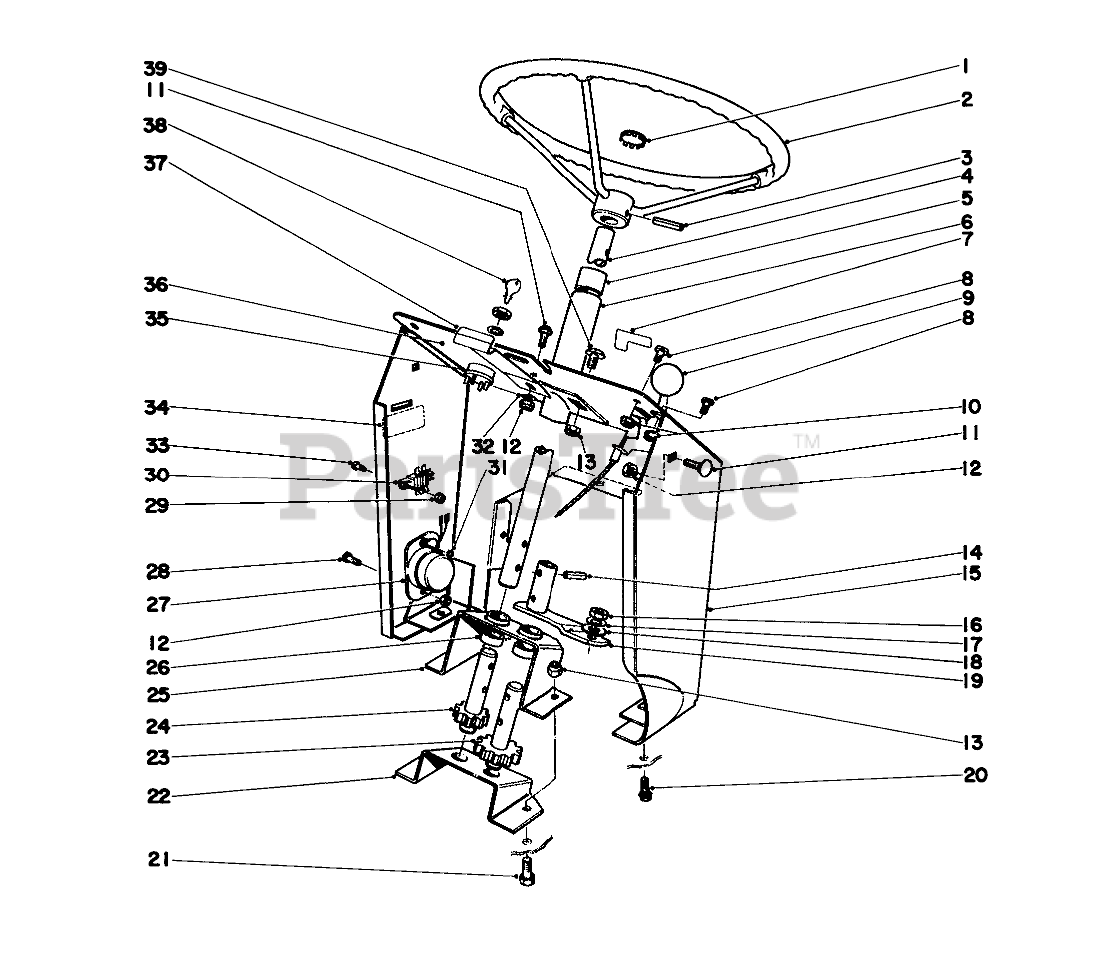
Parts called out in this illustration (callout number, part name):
2	Steering Wheel
3	PIN-ROLL
4	Shaft Steering
5	BUSHING
6	Steering Tube (Incl. Ref. #5)
7	Decal (Model 57003)
8	SCREW-PPH
9	Throttle Control
10	NUT-KEPS
11	SCREW-CARRIAGE
12	NUT-LOCK
13	NUT-LOCK, CONE
14	PIN-ROLL, SLOTTED
15	Rear Hood Support (Model 57003)
16	NUT-HEX
17	WASHER-LOCK
18	WASHER-FLAT
19	Steering Arm
20	1/4-20X5/8 THDG SEMS
21	SCREW-HH
22	Bracket Steering
23	Steering Gear
24	Pinion Gear
25	Support Steering
26	Spacer
27	Ignition Interlock
29	NUT-LOCK, NI
30	Terminal Block
31	WASHER-LOCK/EXT
32	WASHER-FLAT
33	SCREW-HEAD, PAN
34	Decal (Model 56010)
35	Switch
36	Decal Dash (Model 57003)
37	Hood Latch
38	Key
39	Round Head Screw
